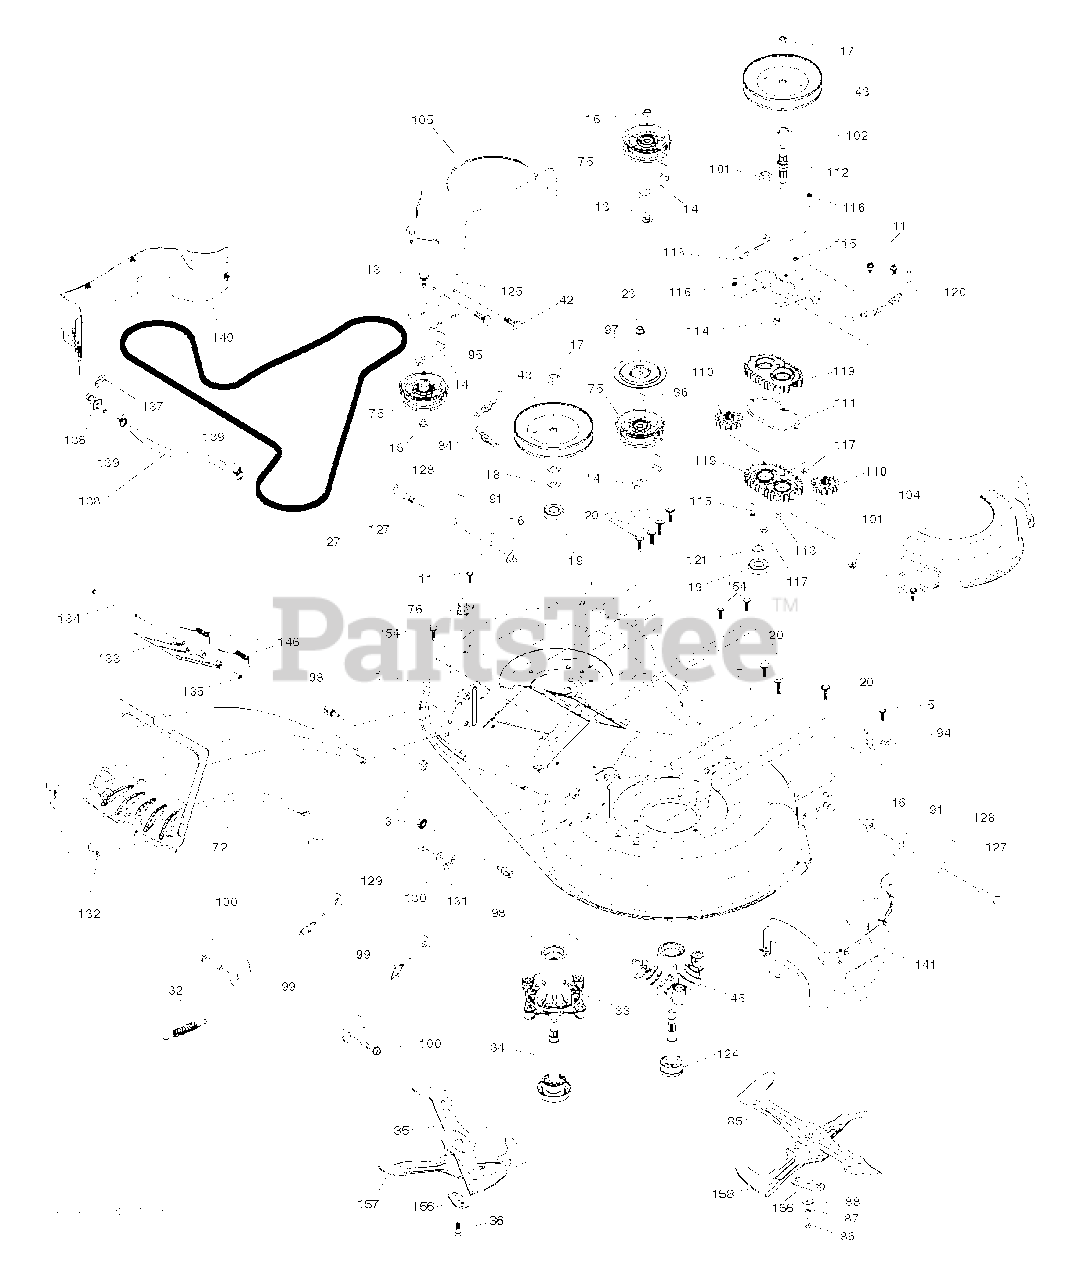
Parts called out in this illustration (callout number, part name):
3	NUT LOCK HEX FLANGE 5/16-18
5	BOLT.5/16HEX.WHS.HD
11	SCREW.1/4-20X5/8
13	BOLT.3/8-16X1.50
14	KEEPER, BELT IDLER
16	NUT LOCK FLG 3/8-16 UNC
17	NUT.FLANGE.LOCK.TOP
18	WASHER.SPACER.MANDREL
20	SCREW, WASHER HEAD
23	SCREW LT
27	BELT BELT. ELECTRIC M
32	SPRING 107CM 97CM ELE
33	HOUSING MANDREL
34	SHAFT.ASM.MDRL.N/GREASE.38
35	BLADE.3N1.LH.CRD
36	BOLT.WASHER.ASM.7/16-2
42	SCREW
43	PULLEY PULLEY MANDREL
45	HOUSING.MANDREL
72	97/107.TEX.CRD.UPPER CHUTE(22)
75	FLAT IDLER PULLEY
76	12 BARB.DECK.WASHOUT.
84	KEEPER KEEPER. LH MAN
85	BLADE.3N1.RH.CRD
86	BOLT.3/8-24X1.25GR8. LHTHRD
87	LOCKWASHER
94	BRKT.CLUTCH.CABLE
95	SCREW, 3/8-16X3/4
98	STUD.FASTNER.W/ANTI-ROTATE
99	ARM.SUSPENSION.MOWER.R
100	BOLT.SHOULDER
101	NUT.CROWNLOCK.9/16 -18.UNC
102	SPACER BEARING
110	RP.CRD.GEAR.OUTPUT
111	GASKET GASKET GEARCAS
113	PLUG PLUG OIL
114	VALVE VALVE RELIEF
115	Screw
116	BOLT.CARIGE.SS.1/4-20X1.75GR5
117	NUT T
118	ARM ARM. CLUTCHING 10
119	GEARCASE GEARCASE SUB
120	KEEPER KEEPER. RH MAN
121	Washer, .687ID X 1OD X 062 THK
124	Mandrel Shaft, Non/Greaseable
125	BRACKET BRACKET IDLER
127	BOLT.SHOULDER.3/8-16X3-5/8
128	WHEEL. GUAGE RALLY
129	ROD ROD. SWAY CRD GEN
130	WASHER
131	PIN.COTTER.5/16.BOW TI
132	KNOB.HANDLE.3/8.TRI-POINT.BLAC
133	COVER DOOR.107 CM CRD
134	Hinge Pin
136	PLUG WASHOUT PORT HOO
138	107.WASHOUT.PORT.HOSE
139	HOSE.3/8.CLAMP (2 2)
140	SUBASM.107.TEX.GEN2.LH.FRENCH
141	GUARD SUBASM. 107 TEX
146	SPRING SPRING EZ MULC
154	SCREW T30 1420 X
156	ADAPTER ADAPTER.CROSS
